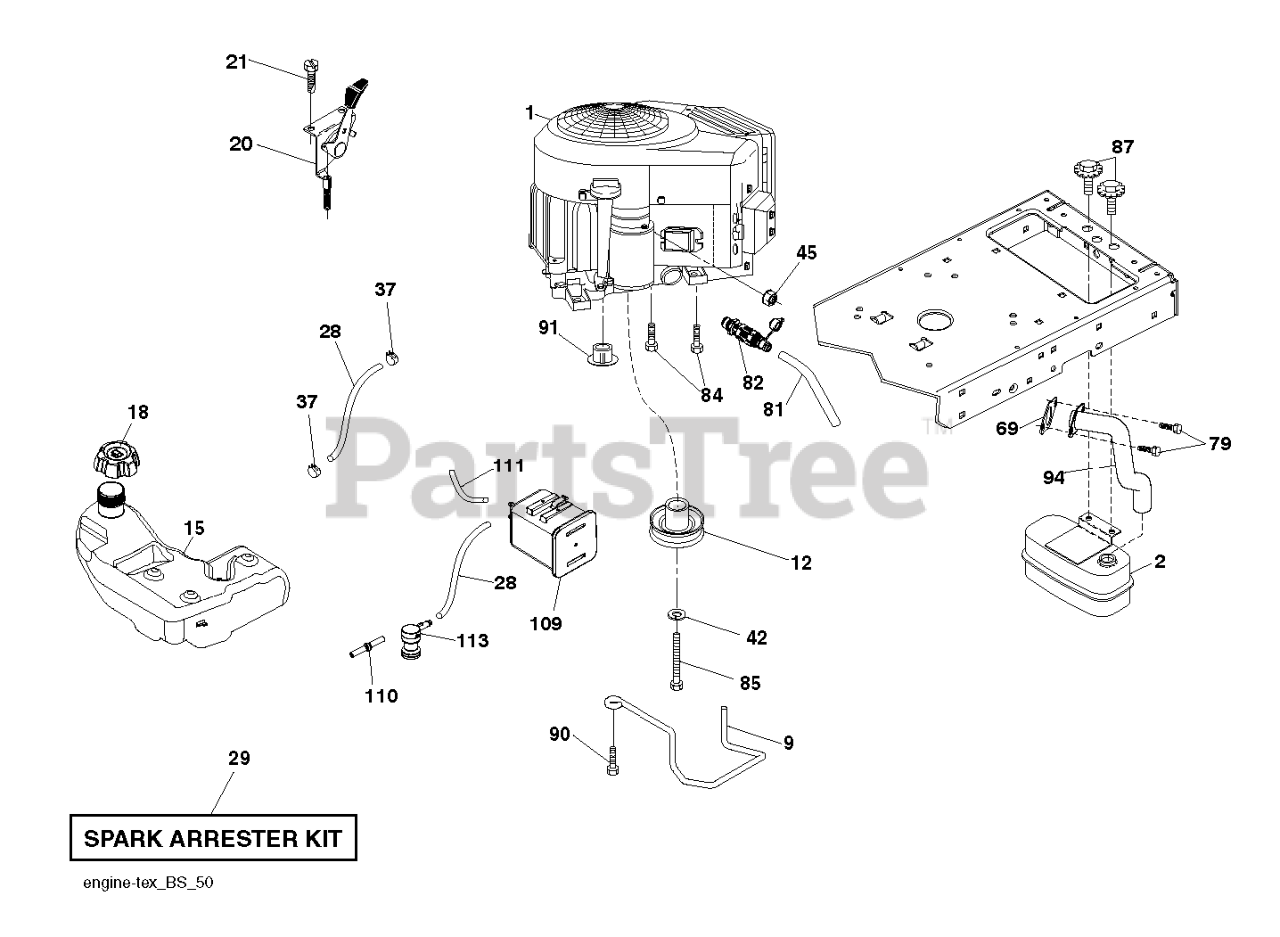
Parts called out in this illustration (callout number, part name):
2	MUFFLER.SINGLE.CYL.KOHL/B&S
9	KEEPER.BELT.ENGINE.4.2
12	PULLY ENGINE
15	TANK.ASM.FUEL.3GA.CARB
18	CAP.ASM.FL.RITCH.3"E10.SYM.498
20	CONTROL.TH/CK.COBRA.KO
21	SCREW.#10 X 0.750.BOS
28	LINE.FUEL.64"REAR.EMIS
29	KIT.SPARK ARRESTOR 794945 B&S
37	HOSE CLAMP
42	LOCKWASHER
45	NUT
69	REPL BY 532 27 22-93
79	SCREW.SOCKET HD.5/16-1
81	TUBE, DRAIN OIL ASM.
82	VALUE.OIL.DRAIN
84	SCREW.3/8-16
85	BOLT HEX 7/16-20X4-1/4"
87	BOLT.5/16-18UNCX3/4 W/SEMS.BLK
90	SCREW 3/8-16X1
91	BUSHING.1.375OD
94	EXHAUST.TUBE.B&S.28/31
109	CANNISTER, CARBON
110	VALVE.ASM.ANTI-SLOSH
111	RP PURGE LINE
113	VALVE.SLANT.CARTRDG.90 DEG.TEX
